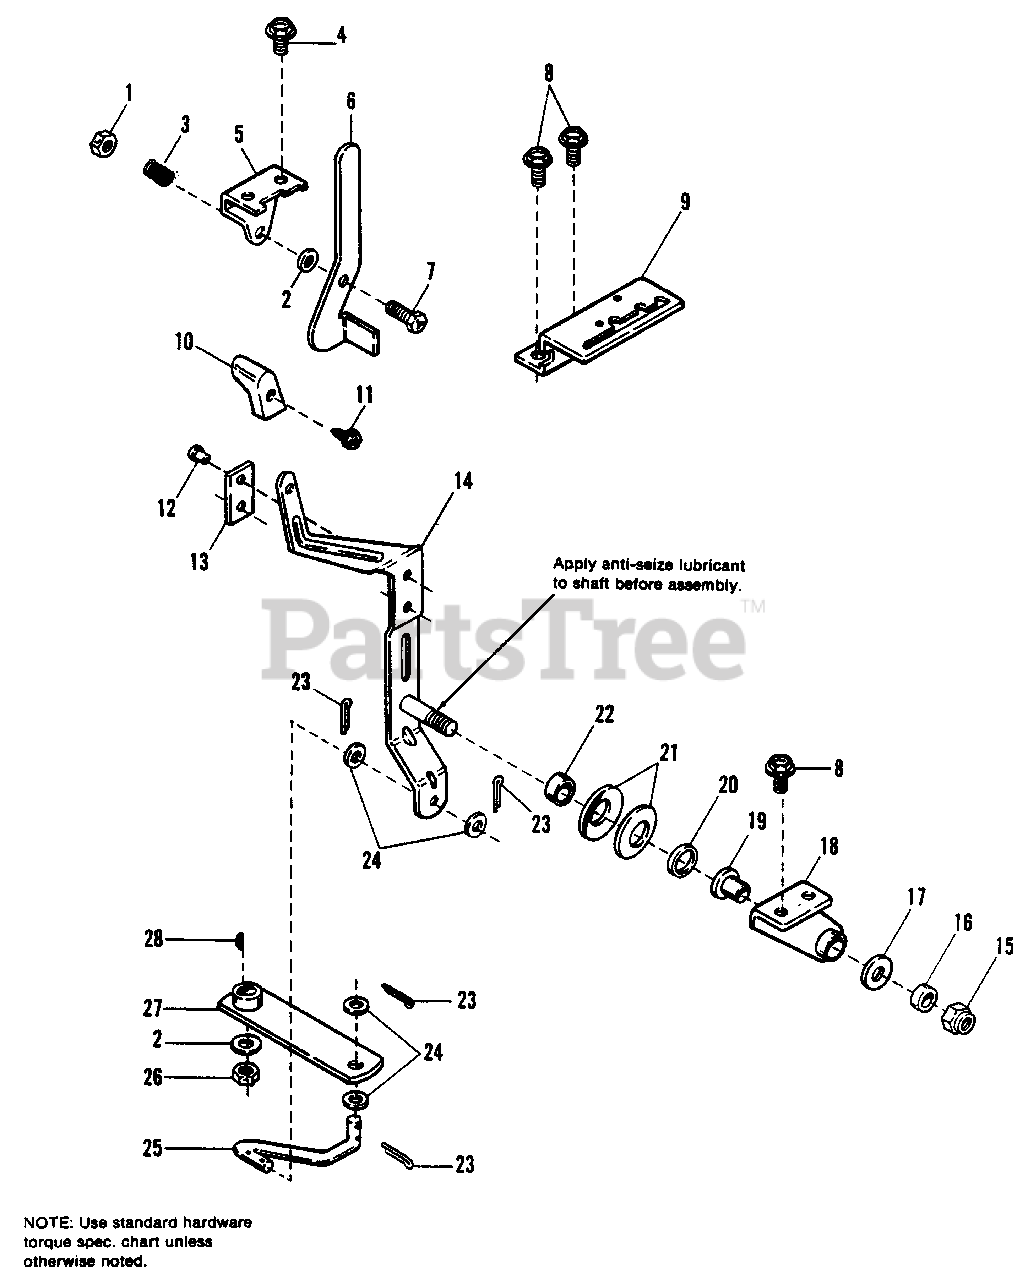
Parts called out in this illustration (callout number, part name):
1	NUT, Hex, Lock, 5/16-18
2	WASHER, Plain, 5/16
3	SPRING, Compression
4	SCREW, Taptite, 1/4-20 x 1/2
5	SUPPORT, Handle, Release Valve
6	HANDLE, Release Valve
7	CAPSCREW, Hex, 5/16-18 x 1-1/4
8	SCREW, Taptite, 5/16-18 x 3/4
11	SCREW,Plastite, 1/4-20 x 1
13	PLATE, Wear
14	LEVER ASSY., Control
15	NUT, Hex, Lock, 5/8-11
18	SUPPORT ASSY. Control
20	WASHER, Special
21	WASHER, Spring
23	PIN, Cotter
24	WASHER, Plain, 13/32 x 7/8
25	LINK, Control
26	NUT, Hex, Lock, 3/8-16
27	ARM ASSY., Control
28	KEY, Woodruff, #3, 1/8 x 1/2
